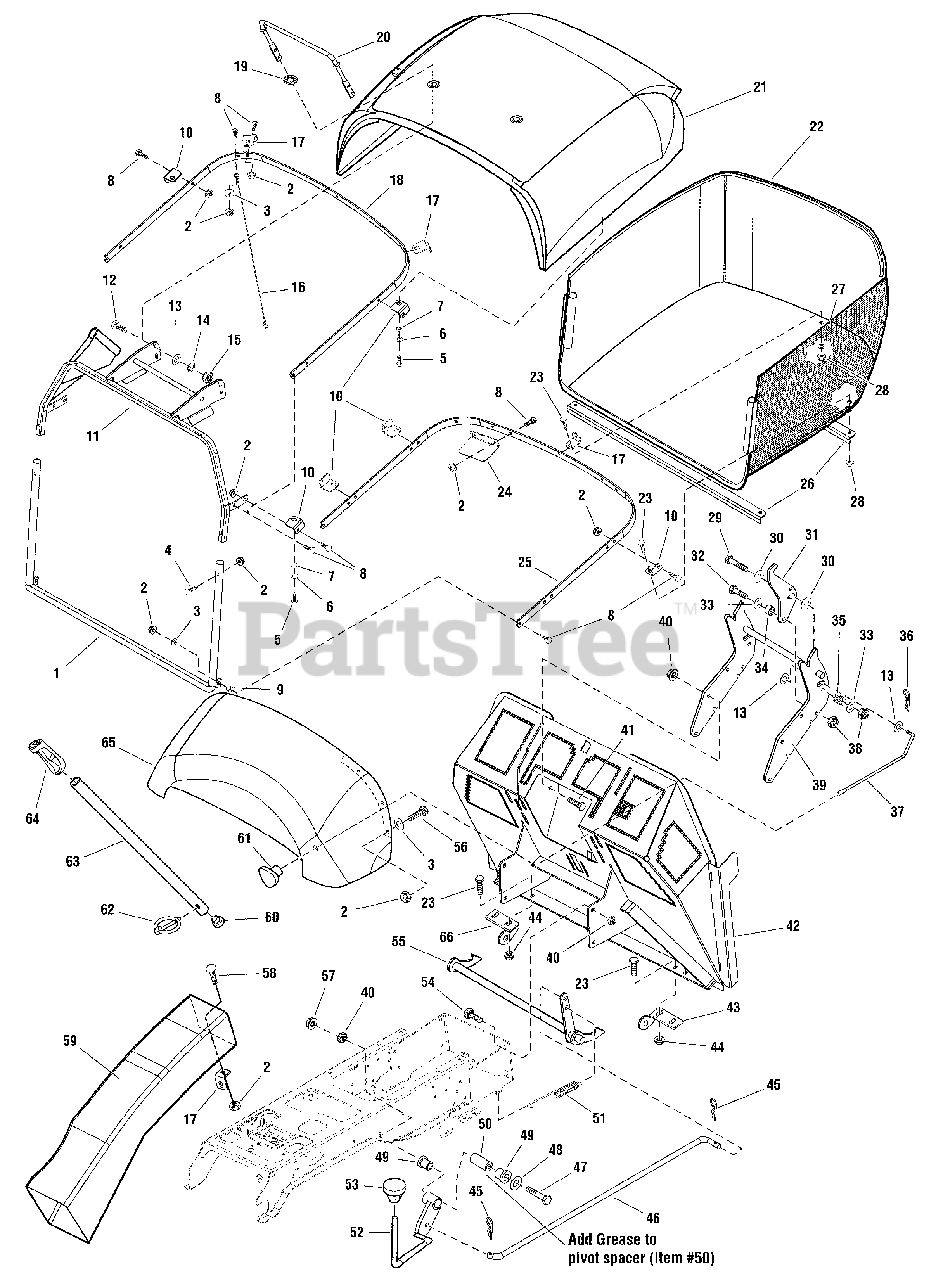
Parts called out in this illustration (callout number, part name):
1	ROD & TABS ASSEMBLY, Bagger Front
2	NUT, Hex KEPS Conical Washer, 1/4-20
3	WASHER, 1/4
4	CARRIAGE BOLT, 1/4-20 x 1-1/4
5	CAPSCREW, Hex Head, 5/16-18 x 1
6	LOCKWASHER, Spring 5/16
7	WASHER, 5/16
8	CARRIAGE BOLT, 1/4-20 x 3/4 G5
10	CLIP, L 12GA
11	FRAME ASSEMBLY, Hopper
12	CAPSCREW, Hex Head, 1/4-20 x 7/8 G5
13	WASHER, 1/4
14	LOCKWASHER, Spring 1/4
15	NUT, Hex 1/4-20
16	CABLE, Bagger, 17.72 Long
17	CLIP, L 12GA
18	BAR, Bagger Top 7GA
19	WASHER, 5/8
20	HANDLE, Hopper, 13.59 Long
21	LID & SCREEN ASSEMBLY, Red
22	BAG, Grass Black Cloth
23	CARRIAGE BOLT, 5/16-18 x 7/8 G5
24	PLATE, Tube Stop Bagger 14GA
25	BAR, Bagger Bottom 7GA
26	BRACE, Angle
27	WASHER, 5/16
28	NUT, Hex KEPS Conical Washer, 5/16-18
29	CAPSCREW, Hex Head 5/16-18 x 2 G5
30	WASHER, 5/16
31	LATCH, Release 10GA
32	CAPSCREW, Hex Head, 5/16-18 x 1
33	WASHER, 5/16
34	SPACER, Powdered Metal
35	SPRING, Compression
36	PIN, Cotter
37	ROD, Foot Pedal Bagger Release, 11.66 Long, 2 Bends
38	NUT, Hex Lock ESNA Light, 5/16-18 NC-3B
39	PIVOT ASSEMBLY, Latch
40	NUT, Hex Flange Whiz Lock, 3/8-16 Large
41	CAPSCREW, Hex Head, 3/8-16 x 3/4 G5
42	BACKPLATE ASSEMBLY
43	BRACKET, Latch LH, 7GA
44	NUT, Hex Flange Whiz Lock, 5/16-18 Small
45	CLIP, Hair Pin, Spring Wire
46	ROD, 25.12 Long, 2 Bends
47	CAPSCREW, Hex Head, 3/8-16 x 2-3/4 G5
48	WASHER, 3/8
49	BUSHING, Powdered Metal
50	SPACER, 1-1/2 Long, Hardened
51	SPRING, Extansion
52	ROD & TUBE ASSEMBLY, Differential Lock Pedal
53	KNOB, Hole 1/2, 1.37 Long
54	CARRIAGE BOLT, 3/8-16 x 1-1/4 G5
55	SHAFT & ARMS ASSEMBLY, Latch
56	SCREW, Pan Head Torx Taptite, 1/4-20 x 3/4
57	NUT, Hex Flange Two Way Lock, 3/8-16 GA
58	CAPSCREW, Hex Head, 1/4-20 x 3/4 G5
59	CHUTE, Discharge Black Poly
60	CAPLUG, Black Poly, 3/4 Hole
61	KNOB, Bagger Release
62	PIN, Klik 5/164
63	HANDLE, Tube, 39.75 Long
64	GRIP, Hopper Lift Rod
65	TRANSITION, Hopper Black
66	BRACKET, Latch RH, 7GA
